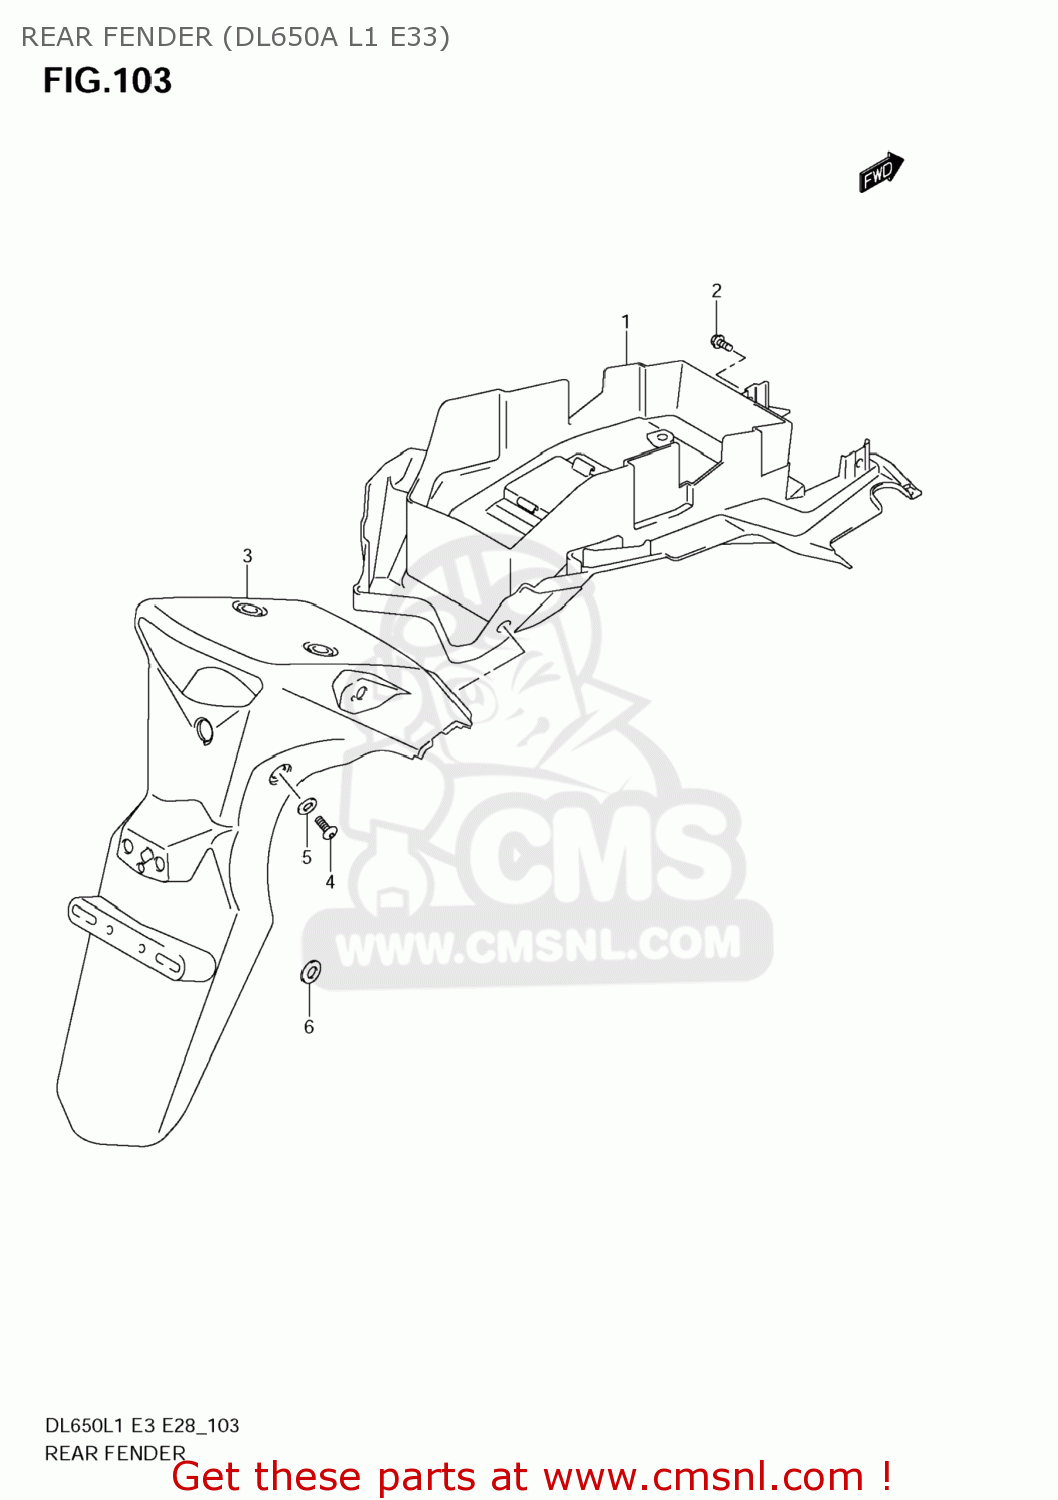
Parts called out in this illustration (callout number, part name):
1	FENDER,RR
2	BOLT(6X12)
3	FENDER,RR RR
4	SCREW(6X16)
5	WASHER(6.5X18X1.6)
6	WASHER
